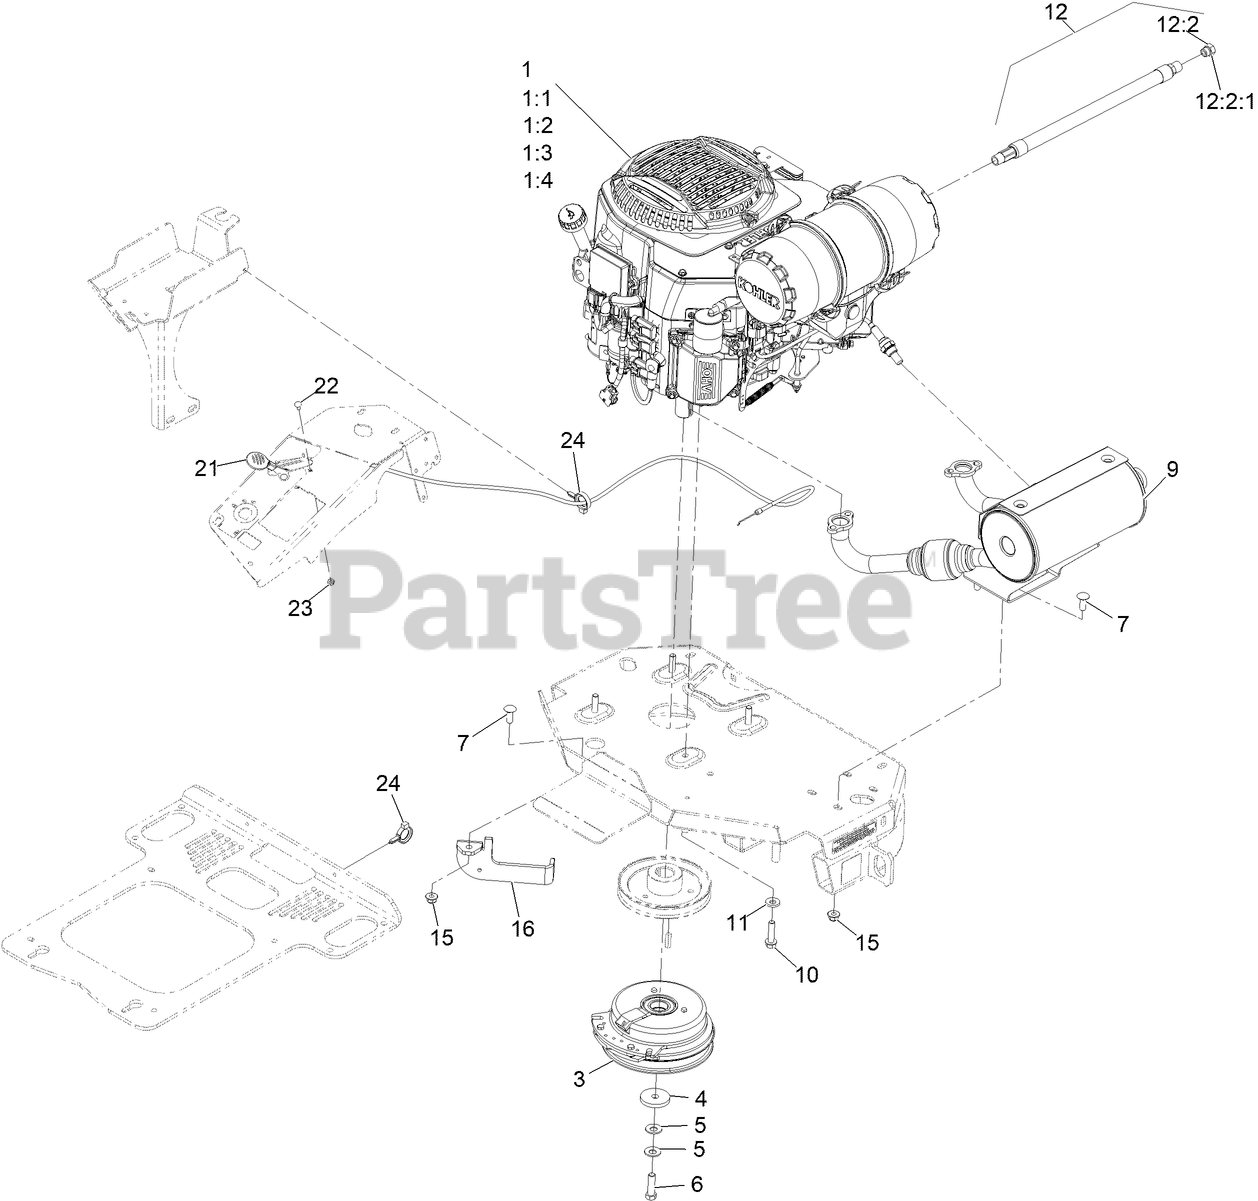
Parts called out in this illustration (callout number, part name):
1:1	Kohler 52 050 02-S Engine Oil Filter
1:2	Kohler 25 083 01-S Engine Air Filter
1:3	Kohler 25 083 04-S Safety Filter
1:4	Kohler 25 050 42-S Fuel Filter
3	CLUTCH KIT
4	WASHER-CLUTCH
5	WASHER-SPRING
6	SCREW-HH 7/16-20 X 1 1/2 W/LOCTITE
7	SCREW-CARR
9	KIT,MUFFLER
10	SCREW-HWH
11	WASHER-BELLEVILLE
12	OIL DRAIN HOSE ASM
12:2	PLUG-HH
12:2:1	O-RING
15	NUT-HF, NI
16	Bracket-Clutch Anchor
21	ASM,THROTTLE CABLE
22	BOLT-CARR
23	NUT-LOCK, NI
24	CLAMP-HOSE
